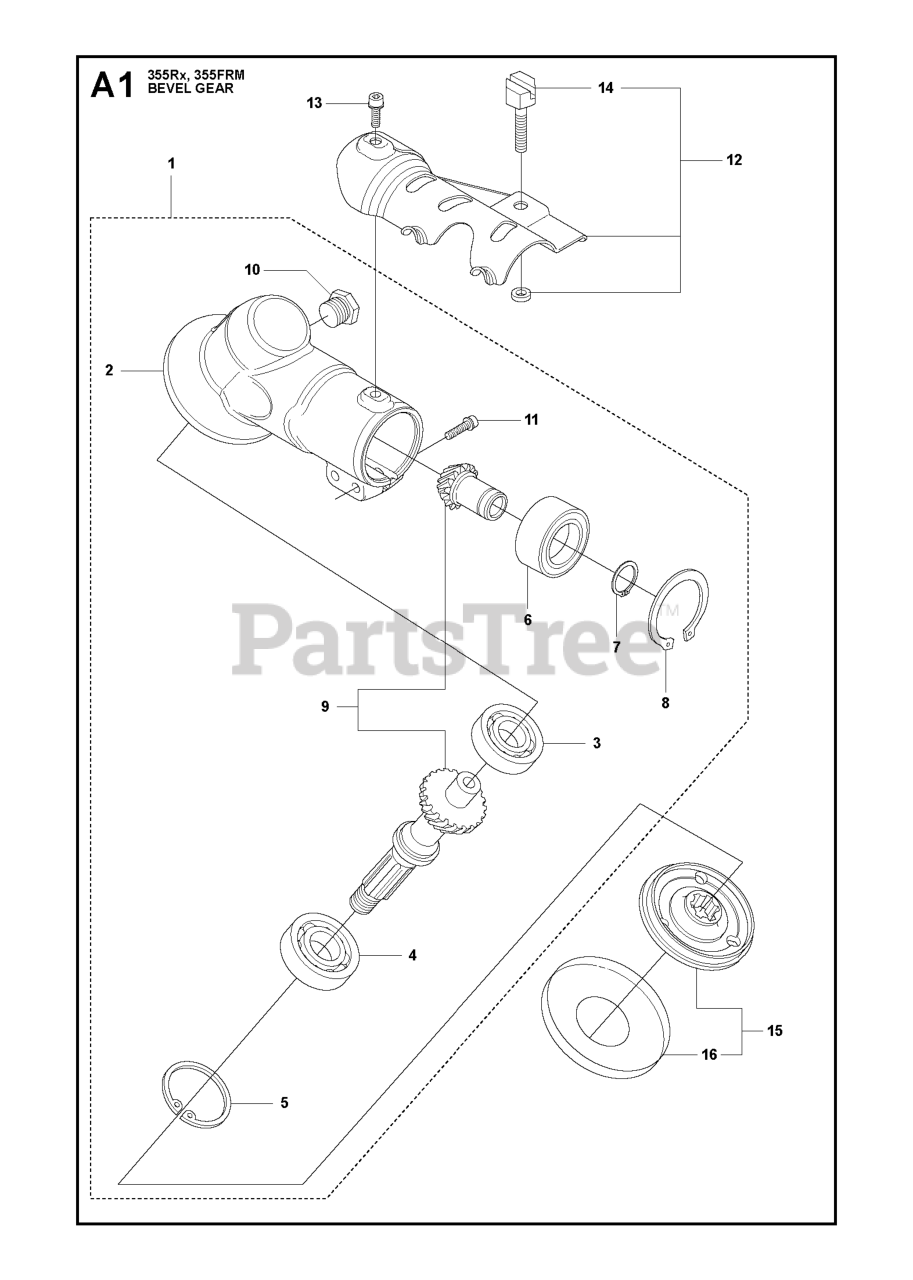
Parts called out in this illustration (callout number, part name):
1	BEVEL GEAR SPARE PART
2	GEAR HOUSING
3	BALL BEARING
4	BALL BEARING
5	RETAINING RING SGH 35
7	RETAINING RING SGA 15
8	RETAINING RING
9	BEVEL GEAR
15	RP CARRIER
16	GRASS SEALING
